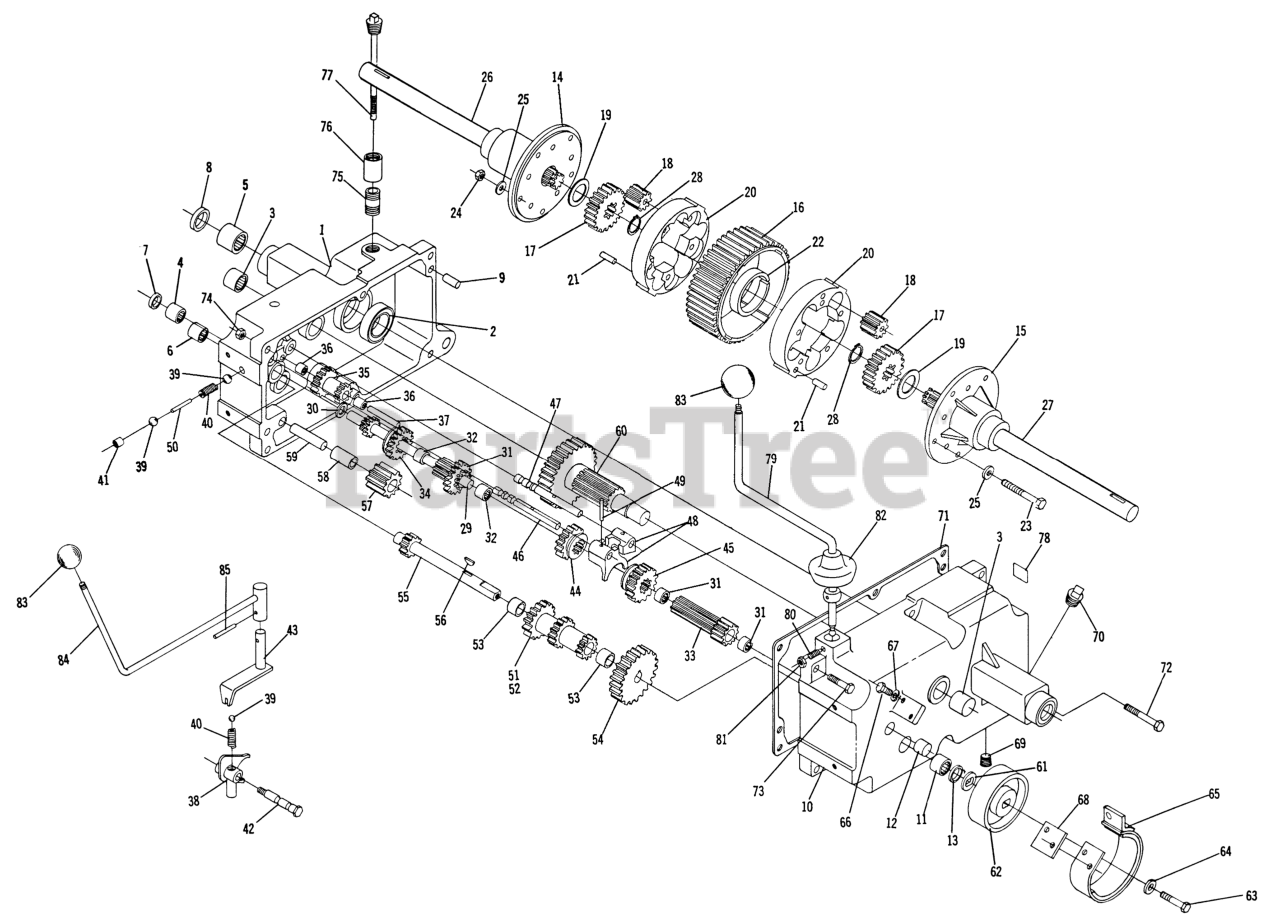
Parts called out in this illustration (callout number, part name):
1	Case RH
2	BALL BRG 1 1/2 I.D.
3	BEARING-NEEDLE
4	BEARING-NEEDLE
5	Bearing-Axle
6	BEARING-NEEDLE
7	Seal 5/8 Shaft
8	Seal
9	PIN-DOWEL
10	Case L.H.
11	BEARING-NEEDLE
12	Bearing Needle
13	Seal
14	End Cap-RH
15	End Cap-LH
16	Gear-Ring
17	SIDE GEAR
18	PINION
19	THRUST WASHER
20	Body
21	SPIROL ROLL PIN
22	Spring
23	Bolt Hex 3 1/4
24	3/8-16 E.S.
25	Washer
26	Axle, R.H.
27	Axle, L.H.
28	SNAP RING
29	SHAFT-INPUT
30	WASHER-THR
31	GEAR
32	BEARING-NEEDLE
33	GEAR
34	GEAR-SLIDING
35	Gear
36	BEARING-NEEDLE
37	GEAR-SHAFT REDUCTION
38	Shift Fork
39	BALL-DETENT
40	Spring
41	CUP-PLUG
42	BOLT-DETENT
43	SHIFT ASM
44	GEAR-HI AND 2ND
45	GEAR-LOW AND REVERSE
46	RAIL-SHIFT
47	RAIL-REAR SHIFT
48	FORK-SHIFT
49	PIN-ROLL
50	PIN-SHIFT
51	GEAR-CLUSTER
52	Cluster Gear
53	BUSHING-BRONZE
54	GEAR-CLUSTER SHAFT
55	Cluster Shaft
56	Key
57	GEAR/BUSHING ASM-REVERSE IDLER
58	BUSHING
59	PIN-DIFFERENTIAL
60	Gear 44T-11T
61	WASHER
62	Drum-Brake
63	Bolt 3/8-16 x 3/4 Nylok
64	WASHER
65	BRAKE BAND ASM
66	Bolt-1/4-20 x 5/8
67	Lockwasher
68	Plate-Stop
69	PLUG 1/4 PIPE ALLEN
70	Plug
71	GASKET-TRANSMISSION
72	Bolt Hex 3/8-16 x 1
73	Bolt, 3/8 16 x 2
75	Nipple Close 1/2 Pipe
76	Coupling 1/2 Pipe
77	Dipstick
78	Decal
79	Shift Stick
80	SETSCREW
81	Nut 1/4-20
82	COVER-DUST
83	Knob
84	Handle-Shift
85	PIN-SPIROL
